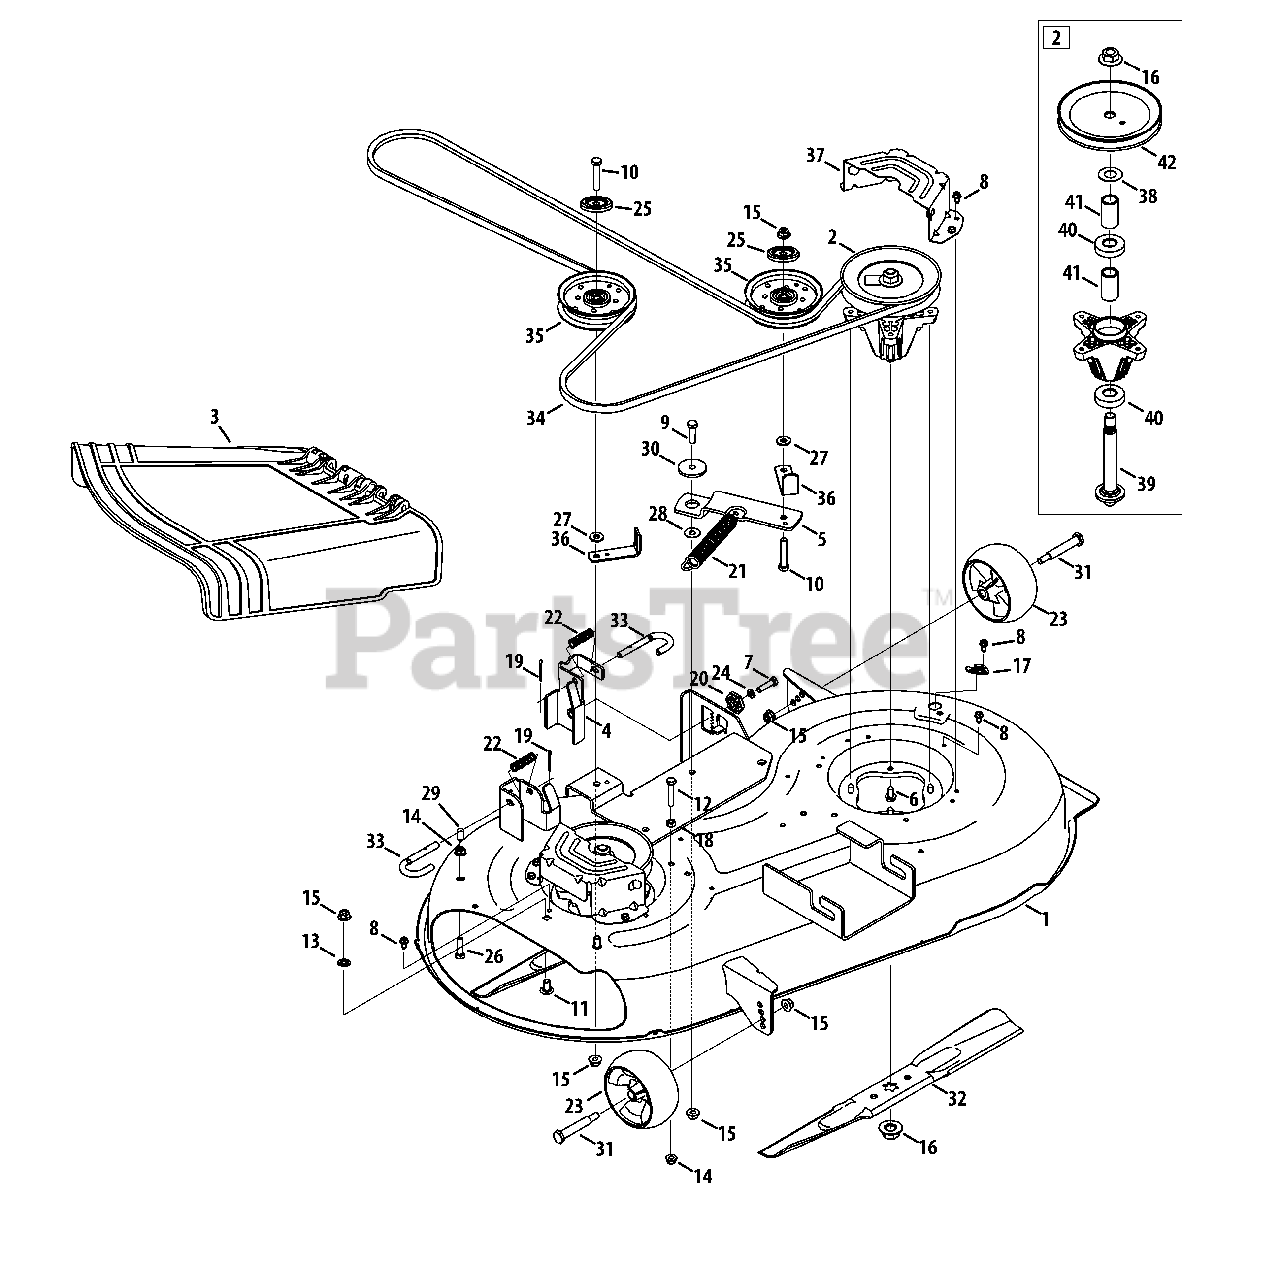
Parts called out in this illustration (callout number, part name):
1	Deck Housing
2	Spindle Assembly
3	Discharge Chute Assembly
4	Deck Lift Bracket
5	Pivot Idler Bracket
6	Self Tapping Screw, 5/16-18 x .75
7	Hex Cap Screw, 5/16-18 x 1.25
8	Hex Washer Head Screw, 1/4-20 x .5
9	Hex Cap Screw, 3/8-16 x 1.25
10	Hex Cap Screw, 3/8-16 x 2.00
11	Carriage Screw, 3/8-16 x .75
12	Hex Cap Screw, 5/16-18 x 1.75
13	Push Nut, 3/8
14	Flange Lock Nut, 5/16-18
15	Flange Lock Nut, 3/8-16
16	Hex Flange Nut, 5/8-18
17	Deck Wash Plug
18	Hex Nut, 5/8-18
19	Cotter Pin, 1/8 x 1.25
20	Deck Adjustment Gear
21	Extension Spring, .94 Dia. x 6.74
22	Compression Spring, .535 x 1.751
23	Deck Ball Wheel, 5.0
24	Lock Washer, 5/16
25	Pulley Cap
26	Hex Cap Screw, 5/16-18 x 1.00
27	Flat Washer, .385 x .870 x .092
28	Flat Washer, .385 x 1.00 x .030
29	Cap, .290 x .500
30	Shoulder Spacer, .884 x .190
31	Shoulder Screw, .5 x 2.5 x 3/8-16
32	Blade, 2 in 1, 21.23
33	Deck Hanger Rod
34	V-Belt
35	Idler Pulley, 4.25 Dia.
36	Bracket, Belt Guard
37	Belt Cover
38	Washer, .760 x 1.50 x .030
39	Spindle Shaft
40	Ball Bearing
41	Spacer, .792 x 1.060 x 1.860
42	Deck Pulley
